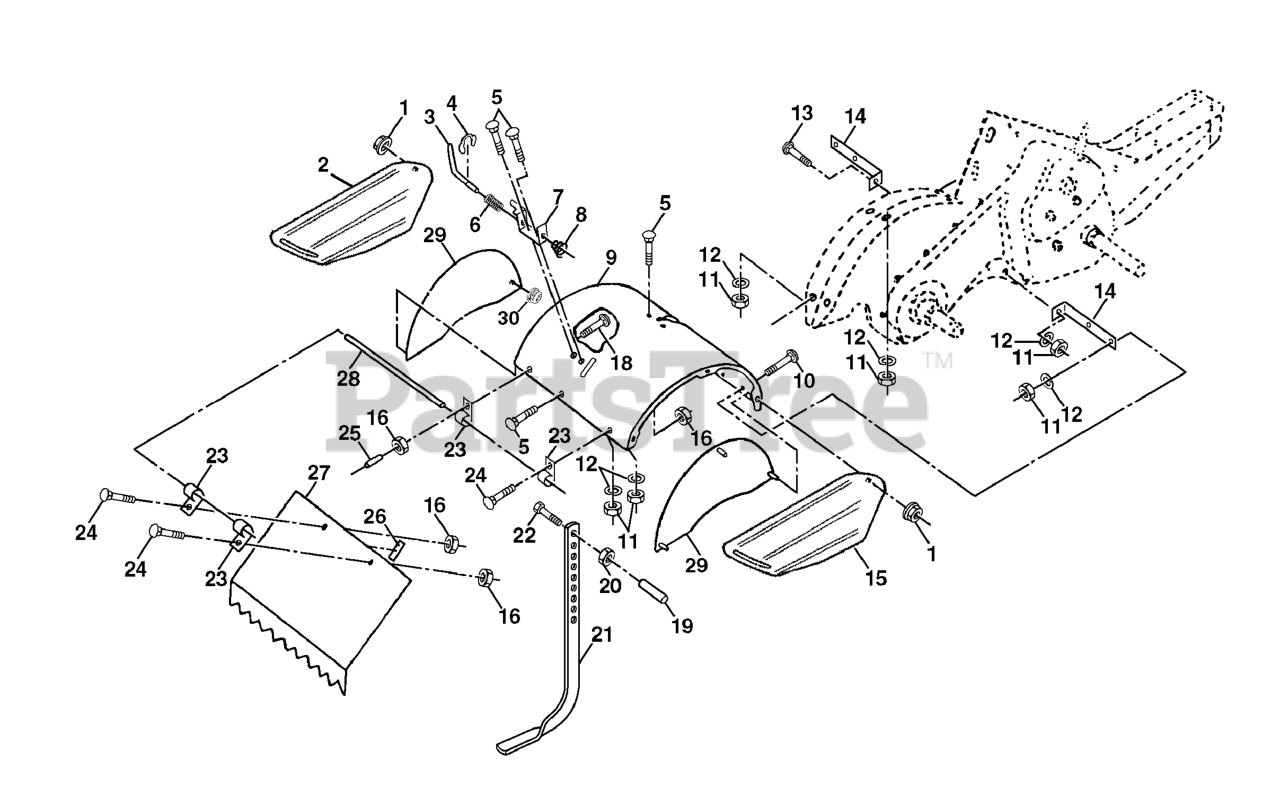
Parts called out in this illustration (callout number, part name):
1	NUT
2	SHIELD
3	STAKE PIN TI
4	KLIP RING TI
5	RP BOLT 5/16-18 X3/4 ZN/YEL GR
7	BRACKET.LATCH.STAKE.3.20.BLACK
8	SPRING CRT
9	SHIELD
10	BOLT
11	NUT
12	WASHER.LOCK.HVY.HLCL.SPR.5/16
13	BOLT.CARRIAGE.5/16-18
14	BRACKET.TINE.SHIELD.TILLER.BLA
15	SIDE SHIELD RH
16	NUT
20	NUT.HEX.3/8-16UNC
21	STAKE.DEPTH.16.CRT.BLACK
22	BOLT.375-16
24	BOLT
25	VINYL CAP TI
26	PAD IDLER TI
27	SHIELD LEVELING
28	PIN.HINGE.TILLER
29	SIDE SHIELD
30	LOCKNUT-FLANGE 5/16-18
